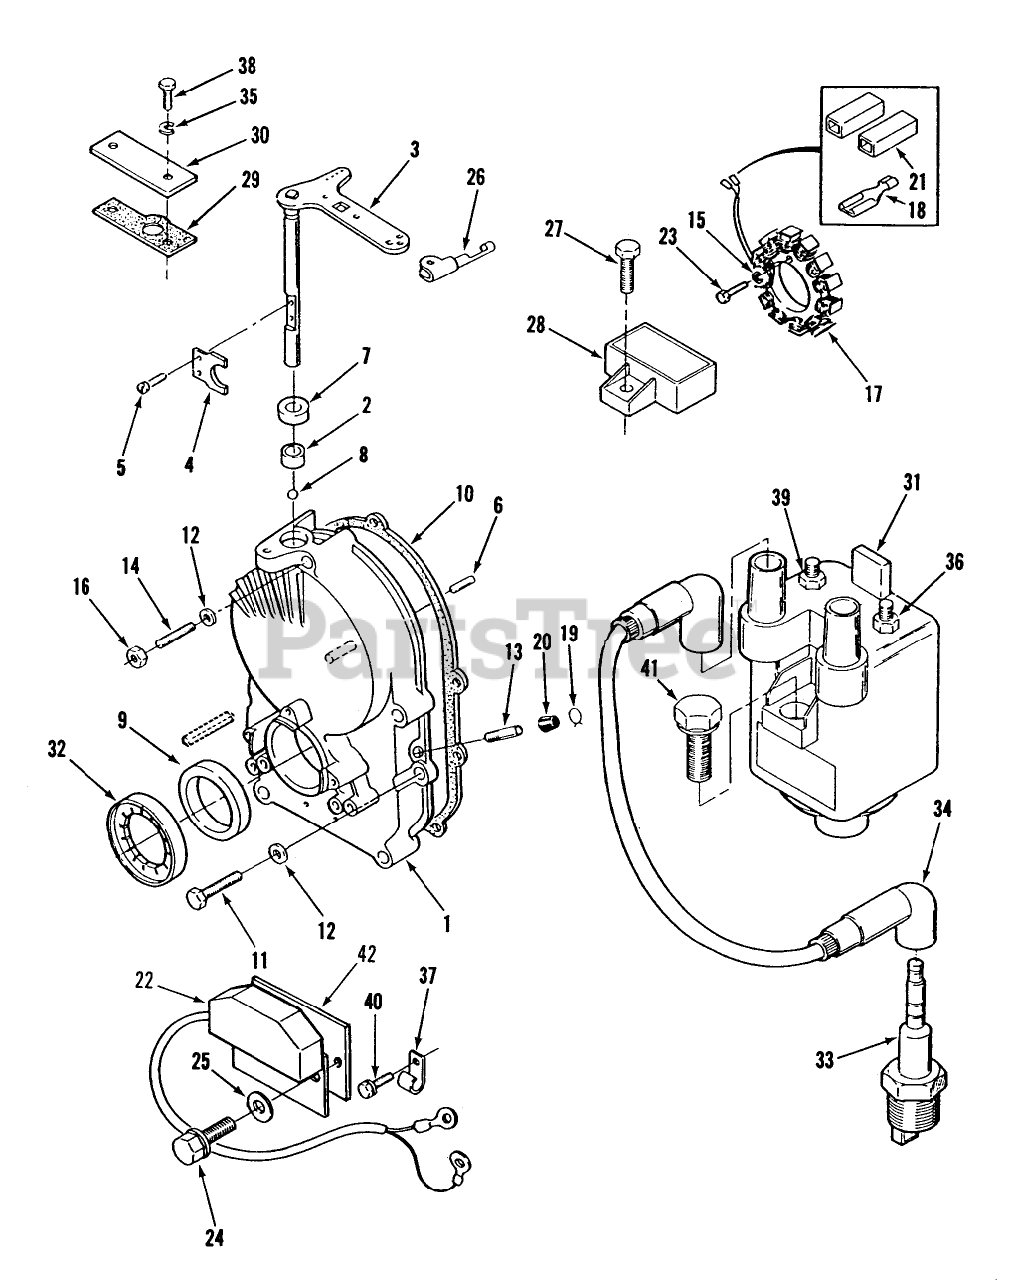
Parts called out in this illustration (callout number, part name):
1	Gearcase Kit (Includes Items 2 thru 9, 13, 19, & 20)
2	Bearing
3	SHAFT AND ARM
4	Yoke
5	Screw
6	Washer
7	Oil Seal
8	Bearing
9	Oil Seal
10	Gasket
11	Screw 5/16-18 1-3/4
12	Washer
13	Vacuum Tube
14	Stud
15	Lockwasher #10
16	Nut
17	Stator w/Terminals
18	Stator Leads Terminal
19	Clamp
20	Cap
21	Terminal Connector Body Kit (Includes Terminals)
22	Control-Ignition
23	Bolt
24	Bolt
25	Lockwasher
26	Clip-Retaining
27	Bolt
28	Regulator
29	Gasket
30	Plate
31	Coil-Ignition
32	Rotor
33	Plug-Spark
34	Wire-Plug
35	Washer-Lock
36	Nut
37	Clip
38	Bolt
39	Nut
40	Screw-Cap Hex Hd.
41	Bolt
42	Insulator
